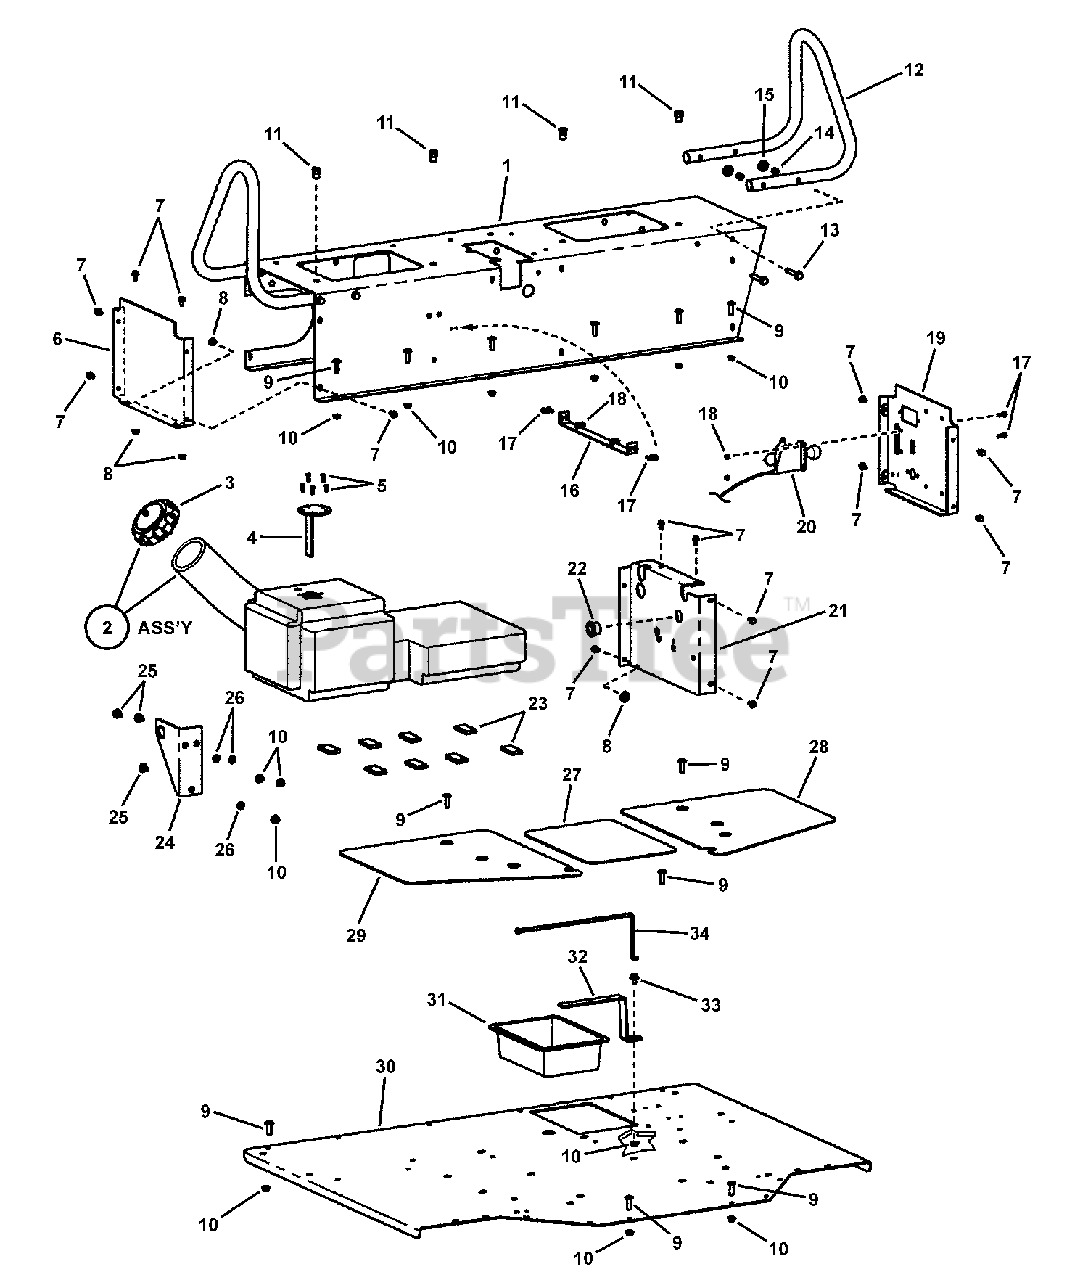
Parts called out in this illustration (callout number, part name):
1	PEDESTAL, Seat, Red
1	PEDESTAL, Seat, Green
2	GAS TANK, UV
3	GAS CAP
4	SENDING UNIT, UV gas tank
5	SCREW, #10-24 x 1/2" Pan Head Machine
6	ENDCAP, Red
6	ENDCAP, Green
7	SCREW, 1/4-20 x 1/2" Hex Flange Lock, GR 5
8	NUT, 1/4-20 Hex Flange Lock, GR 5
9	SCREW, 5/16-18 x 1" Cross Recessed Round Hd Mach. GR 5
10	NUT, 5/16-18 Hex Flange Lock, GR 5
11	INSERT, 5/16-18 Hex Threaded
12	HANDLE, Seat Pedestal
13	BOLT, 5/16-18 x 2" Hex Flange Lock, GR 5
14	WASHER, .375 x .875 x .083 Flat
15	NUT, 5/16-18 Hex Nyloc
16	GAS TANK STRAP
16	GAS TANK STRAP (Trailmaster version)
17	SCREW, #10-32 x 5/8 Hex Washer Head Machine
18	NUT, #10-32 Hex Nyloc
19	WELDMENT, Power Generator End Cap, LH (Red)
19	* WELDMENT, Power Generator End Cap, LH (Green)
20	THROTTLE, Remote, Powerlink
21	BRACKET, Seat Pedestal Support
21	BRACKET, Seat Pedestal Support (Green)
22	BEARING, 3/4" I.D.
23	PAD - Gas Tank
24	SPOT CAM PIVOT
25	BOLT, 5/16-18 x 5/8" Short Square Neck Carriage, GR 5
26	RETAINER, 5/16" Bolt
27	FOOTPAD, Center, UV-2
28	FOOTPAD, LH, UV-2
29	FOOTPAD, RH UV-2
30	FLOORPAN, Red
30	FLOORPAN, Green
31	TRAY, Battery
32	BRACKET, Battery Hold Down
33	BOLT, 5/16-18 x 1/2" Hex Flange Lock
34	RETAINER, Battery (Rod)
